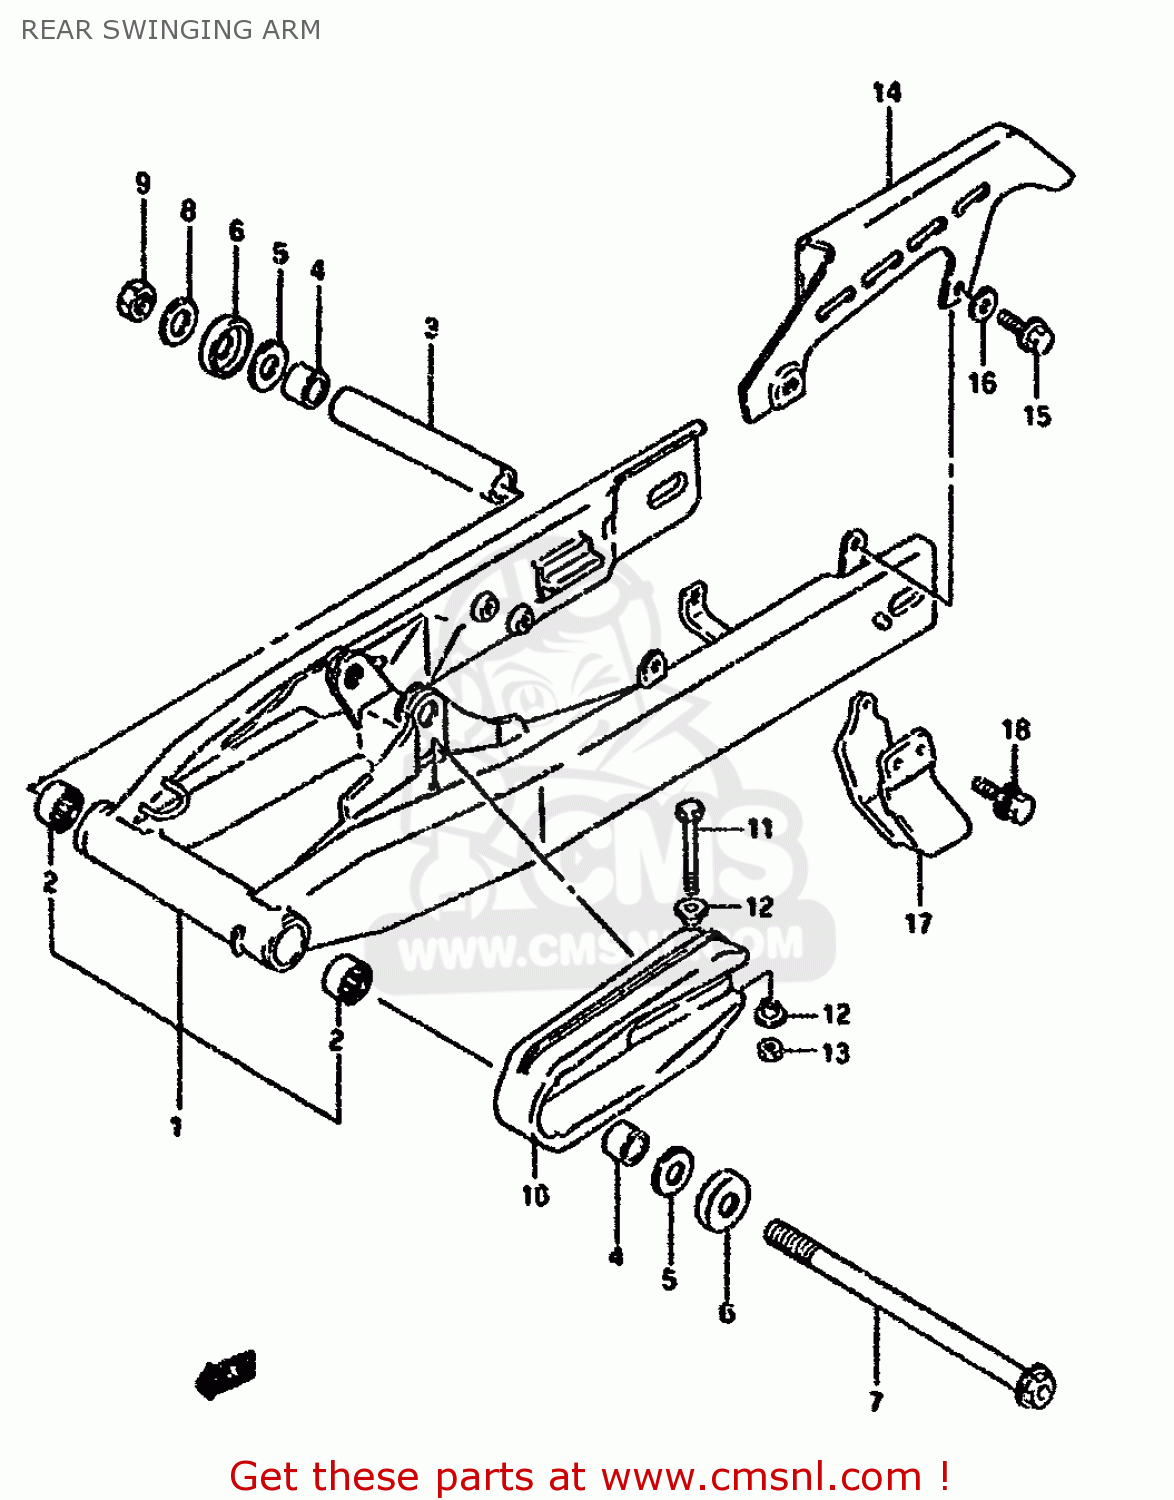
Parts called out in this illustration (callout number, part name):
1	SWINGING ARM ASSY,REAR (SILVER)
2	BEARING(22X29X20)
3	SPACER,RR SWGARM PIVOT CTR
4	SPACER,RR SWGARM PIVOT
5	WASHER
6	SEAL,RR SWGARM PIVOT DUST
7	SHAFT,REAR SWING ARM
8	WASHER
9	NUT 16MM
10	BUFFER,CHAIN TOUCH DEFENSE
11	BOLT,CHAIN TOUCH DEFENCE,FTG
12	WASHER
13	NUT
14	CASE,CHAIN
15	BOLT
16	WASHER
17	GUIDE,CHAIN
18	BOLT
